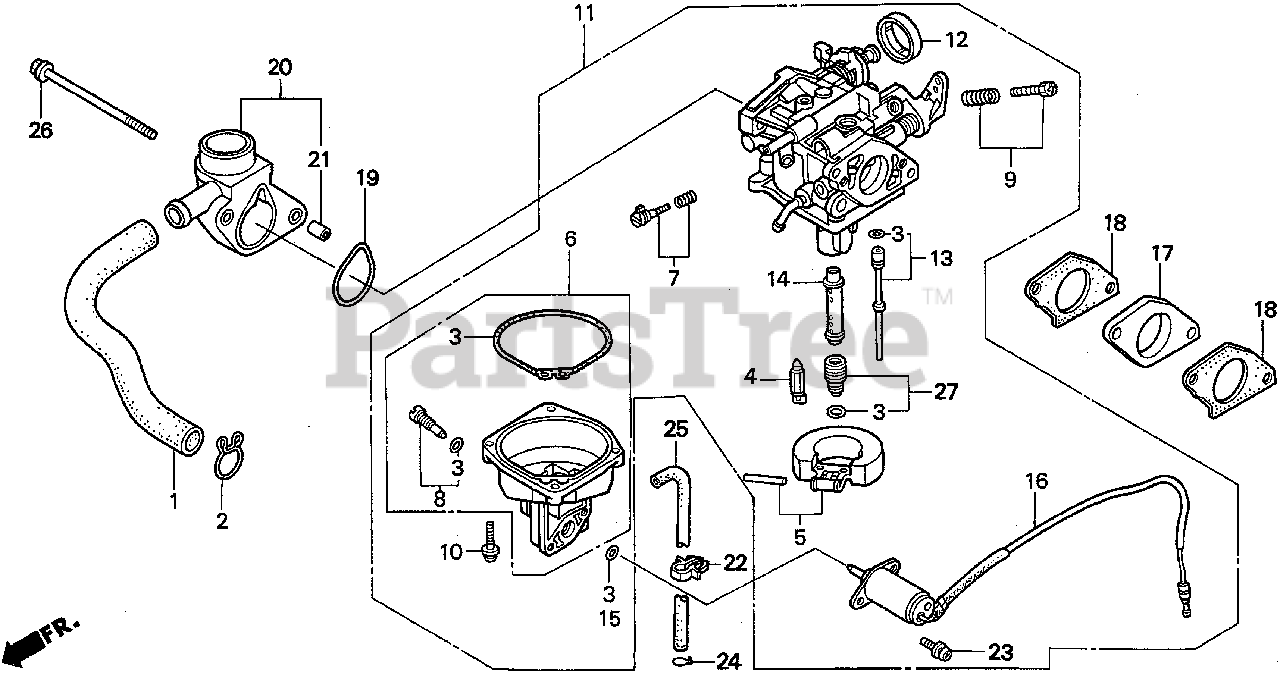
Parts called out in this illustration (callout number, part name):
1	TUBE, BREATHER
2	CLIP, BREATHER TUBE
3	GASKET SET
4	VALVE SET, FLOAT
5	FLOAT SET
6	CHAMBER SET, FLOAT
7	SCREW SET
8	SCREW SET, DRAIN
9	SCREW SET
10	SCREW-WASHER
11	CARBURETOR ASSY. (BG22A C)
12	CAP, CHOKE LEVER DUST
13	JET SET (#45)
14	NOZZLE, MAIN
15	O-RING (5.8X1.9)
16	VALVE ASSY., SOLENOID
17	INSULATOR, CARBURETOR
18	GASKET, CARBURETOR
19	GASKET, AIR CLEANER
20	ELBOW, AIR CLEANER
21	COLLAR, DISTANCE
22	CLIP B, CABLE
23	SCREW-WASHER (5X12)
24	CLIP, TUBE (B8)
25	BULK HOSE, VACUUM (4.5X1000) (4.5X460)
26	BOLT, FLANGE (6X105)
27	JET SET, MAIN (#90)
27	JET SET, MAIN (#92)
27	JET SET, MAIN (#95)
